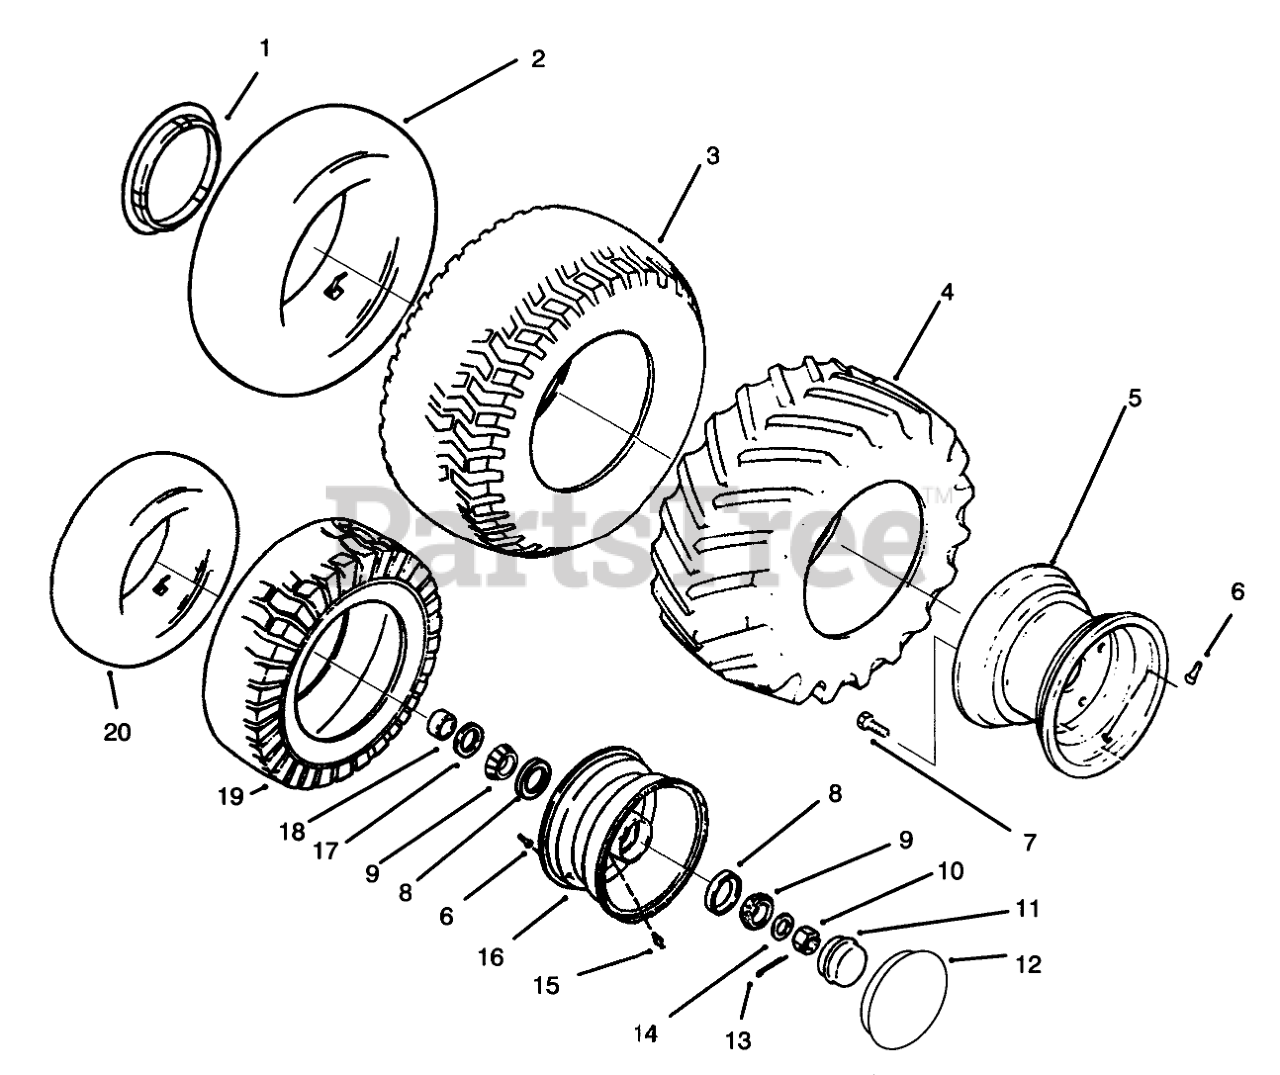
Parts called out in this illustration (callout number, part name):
1	12"-HUB CAP LOGO
2	Rear Tube
3	TIRE-16 X 7.50 TURF
4	Tire-Cleat, Rear
5	RIM ASM
6	VALVE
7	BOLT-LUG
8	Cup
9	Bearing
10	NUT-HEX, SLOTTED
11	DUST CAP
12	8"-HUB CAP LOGO
13	PIN-COTTER
14	WASHER
15	ZERK-GREASE
16	Wheel-Front (Includes Item 15 & Qty. 2 of Item 8)
17	Seal
18	SPACER
19	TIRE 23 X 10.50-12
